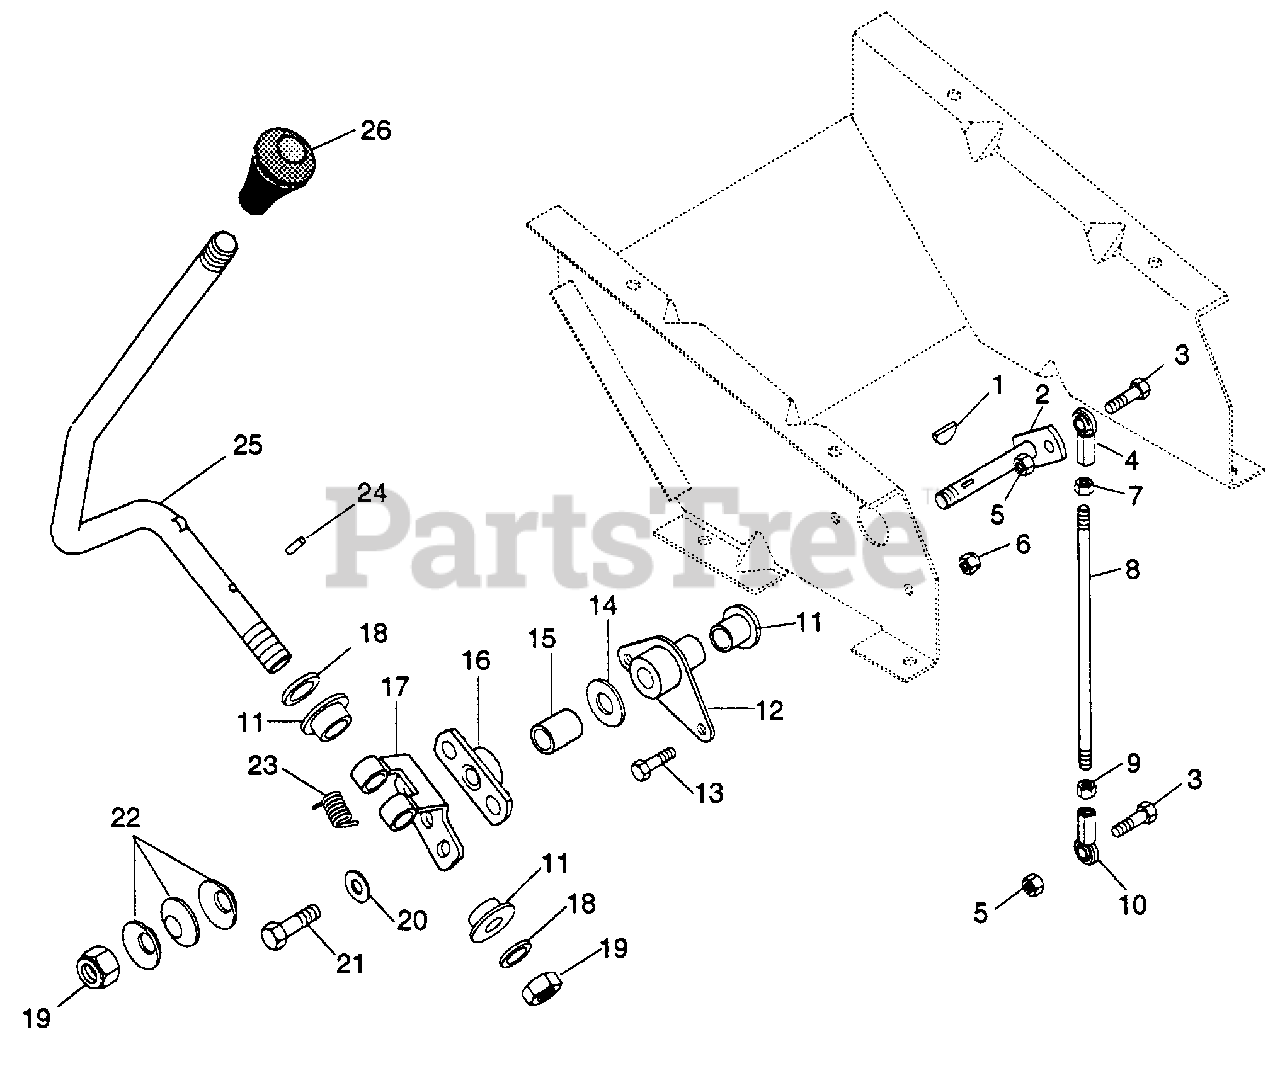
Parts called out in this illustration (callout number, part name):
1	Key, Wdrf 1/8 x 1/2 Hdr #3
2	Rod
3	Blt-Hex .25-20 x .63 Pl Gr 2
4	Rod End RH
5	Nut-Lk-Nyl .250-20 Pl
6	Nut-Lk-Nyl .312-18 Pl
7	Nut-Hex .250-28
8	Shift Rod
9	Nut-LH .250-28 Gr 2 Pl
10	Rod End LH
11	Bshg-Flg .500 x .625 x .625 x .875
13	Blt-Hex .31-18 x 1.00 Pl Gr 5
14	Friction Washer
15	Bshg-Slv .500 x .625 x .500
16	Arm
17	Outer Arm
18	Wshr-Fl-Stl .531 x 1.000 x .063
19	Nut-Lk .50-20 Pl
20	Wshr-Fl-Stl .406 x .812 x .065 Pl
21	Blt-Hex .38-16 x 1.00 Pl Gr 5
22	Spring Washer
23	Sg-Tors .08 x .56 x .65
24	Pin, Spring .125 x 1.000
25	Shift Lever
26	Knob
